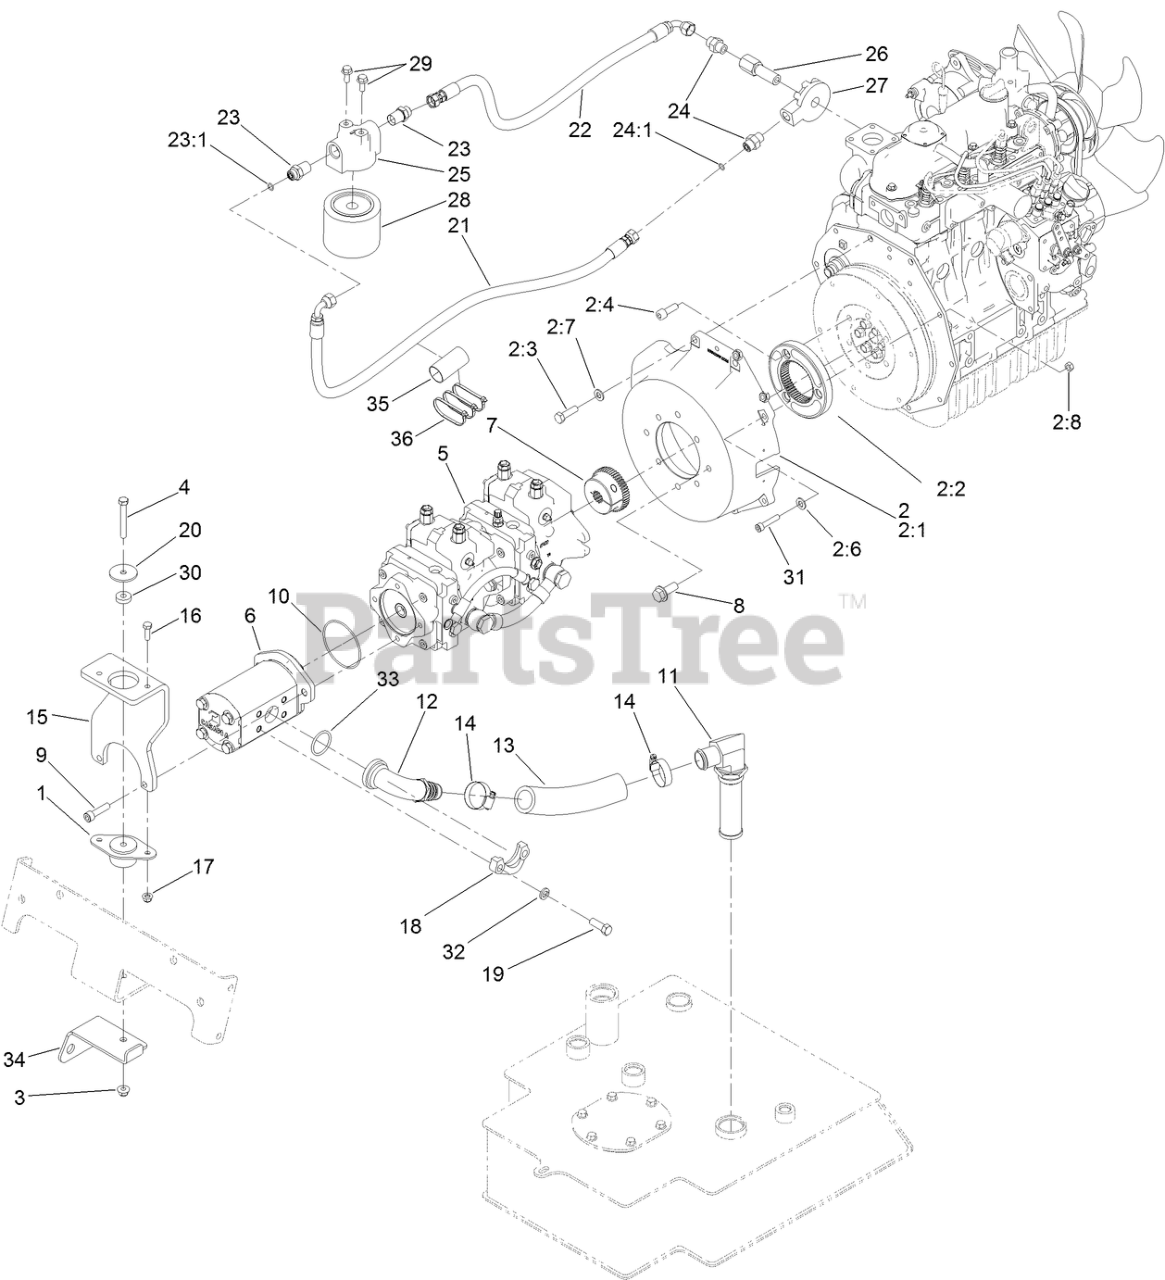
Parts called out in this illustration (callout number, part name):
1	MOUNT-ENGINE
2	MOUNT-PUMP
2:1	HOUSING-PUMP MOUNT
2:2	FLANGE-COUPLER
2:3	SCREW-HH
2:4	SCREW-HSH
2:6	WASHER-PLAIN
2:7	WASHER-FLAT
2:8	NUT-HEX
3	NUT-HF, NI
4	SCREW-HH
5	PUMP-TANDEM
6	PUMP-GEAR
7	HUB-PUMP
8	SCREW-HHF
9	SCREW-SH
10	O-RING
11	STRAINER-SUCTION
12	FITTING
13	HOSE-SUCTION
15	BRACKET-SUPPORT, PUMP
16	SCREW-HH
17	NUT-HF, NI
18	FLANGE
19	SCREW-HH
20	WASHER-REBOUND
21	HYD HOSE ASM
22	HYD HOSE ASM
23	FITTING-HYD
23:1	O-RING
24	FITTING-HYD
24:1	O-RING
25	BASE-FILTER
26	PIPE-JOINT
27	BASE-FILTER
28	FILTER-OIL
29	SCREW-HHF
30	SPACER
31	SCREW-HSH
32	WASHER-LOCK
33	O-RING
34	BRACKET-BULKHEAD
35	PROTECTOR-HOSE
36	TIE-CABLE
